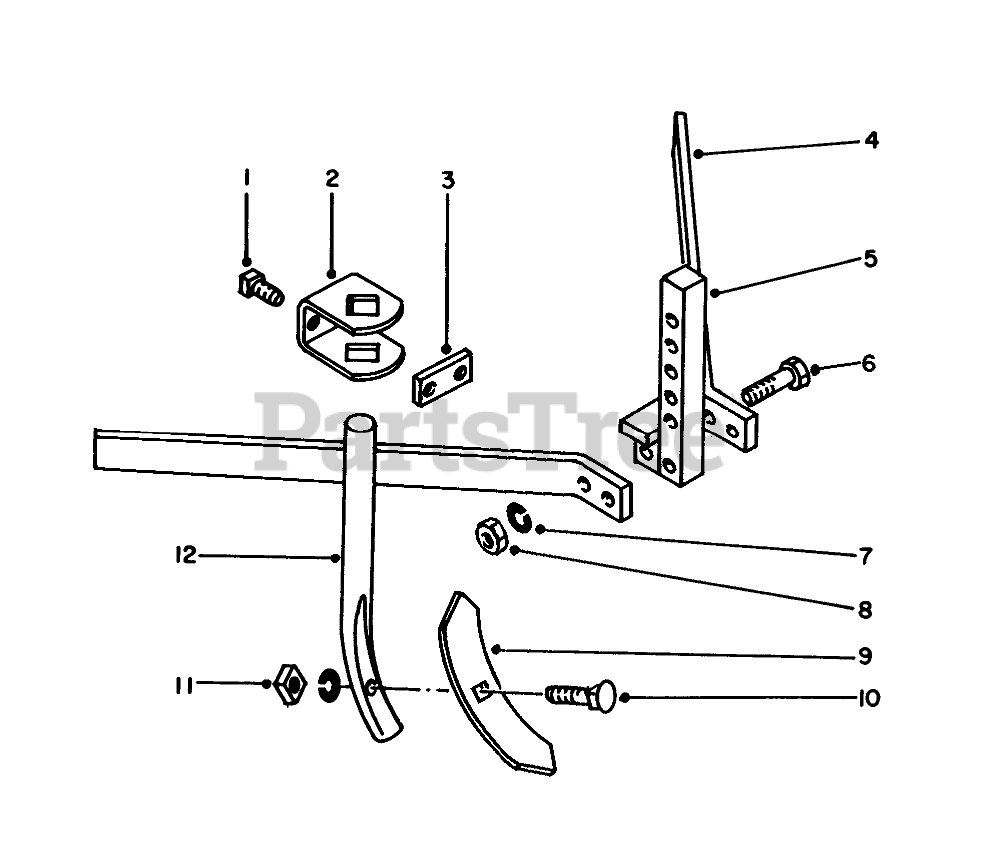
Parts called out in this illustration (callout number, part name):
1	Set Screw
2	Clamp
3	Special Nut
4	Hitch Side-A Frame
5	Hitch
6	SCREW-HH
7	WASHER-LOCK
8	NUT-HEX
9	Wishbone Harrow Point
10	Plow Bolt
11	Square Nut
12	Attachment Standard
